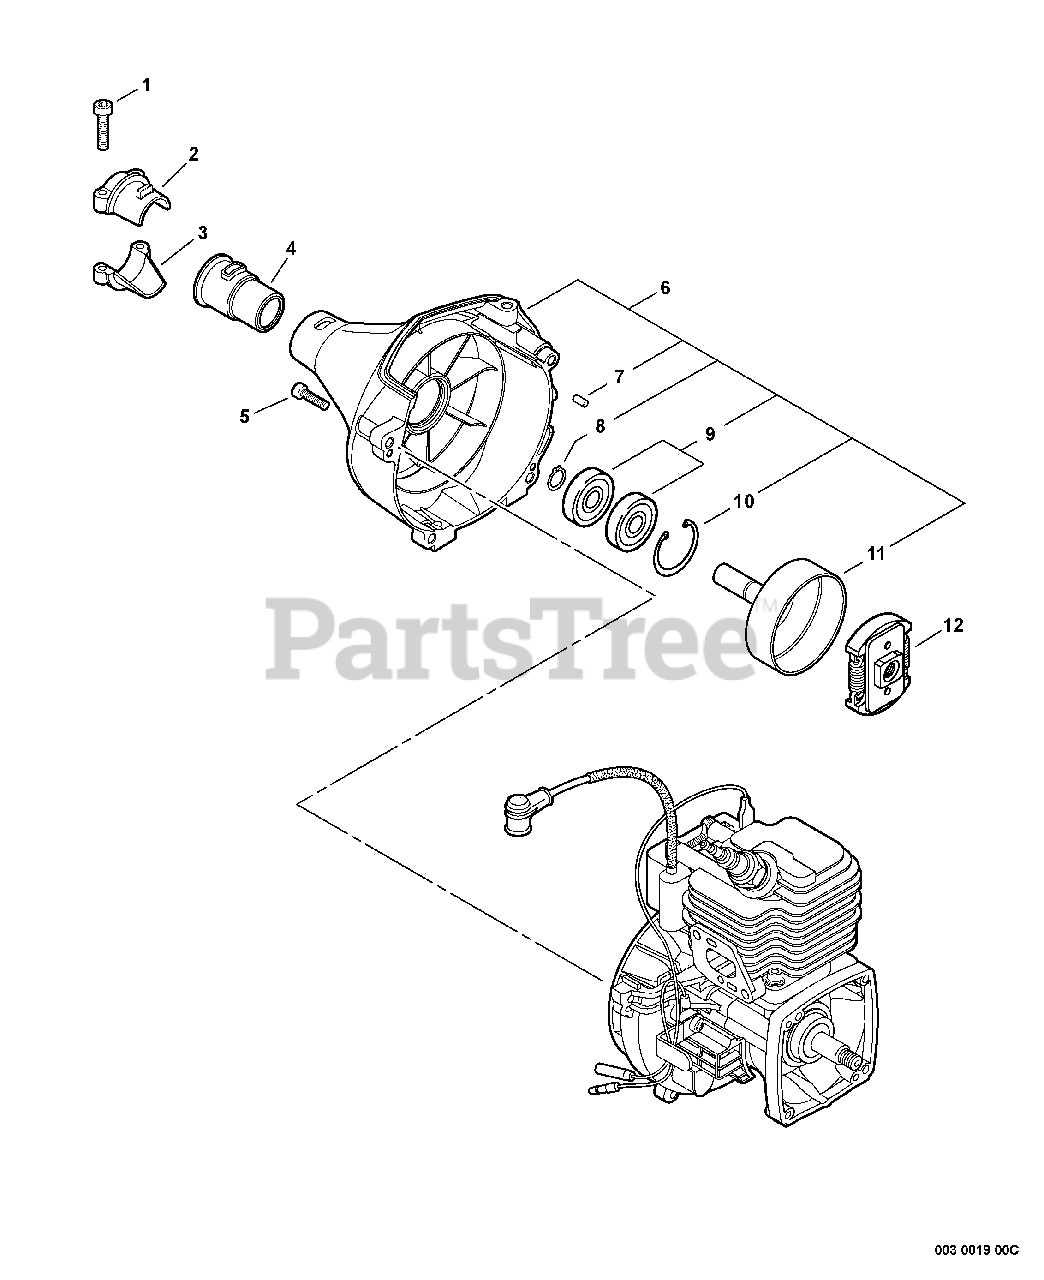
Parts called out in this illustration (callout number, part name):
1	SCREW - 5X20
2	CLAMP, MAIN PIPE - UPPER
3	CLAMP, MAIN PIPE - LOWER
5	SCREW - 4X16
6	FAN CASE ASSY
7	PIN - LOCATING
8	RING, RETAINING - 12
9	BEARING, BALL - 6001
10	RING, RETAINING - 28
11	DRUM, CLUTCH
12	CLUTCH ASSY
